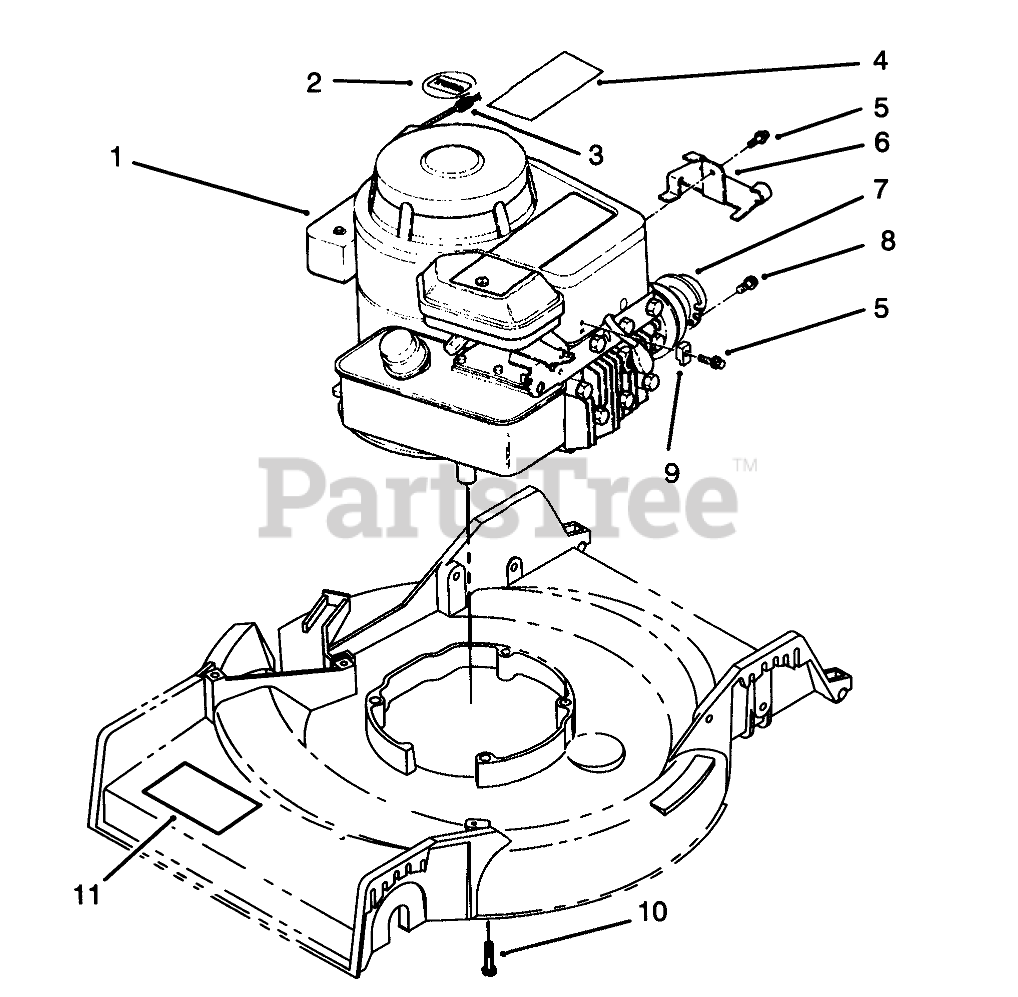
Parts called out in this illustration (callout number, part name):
2	Decal-Toro
3	STOP-ROPE
4	Decal-Engine
5	CLAMP SCREW F/W ENGINE
6	CABLE BRACKET
7	MUFFLER DEFLECTOR F/W
8	SCREW W/ENGINE
9	CASING CLAMP F/W ENGINE
10	THD FORM SCREW
11	DECAL
